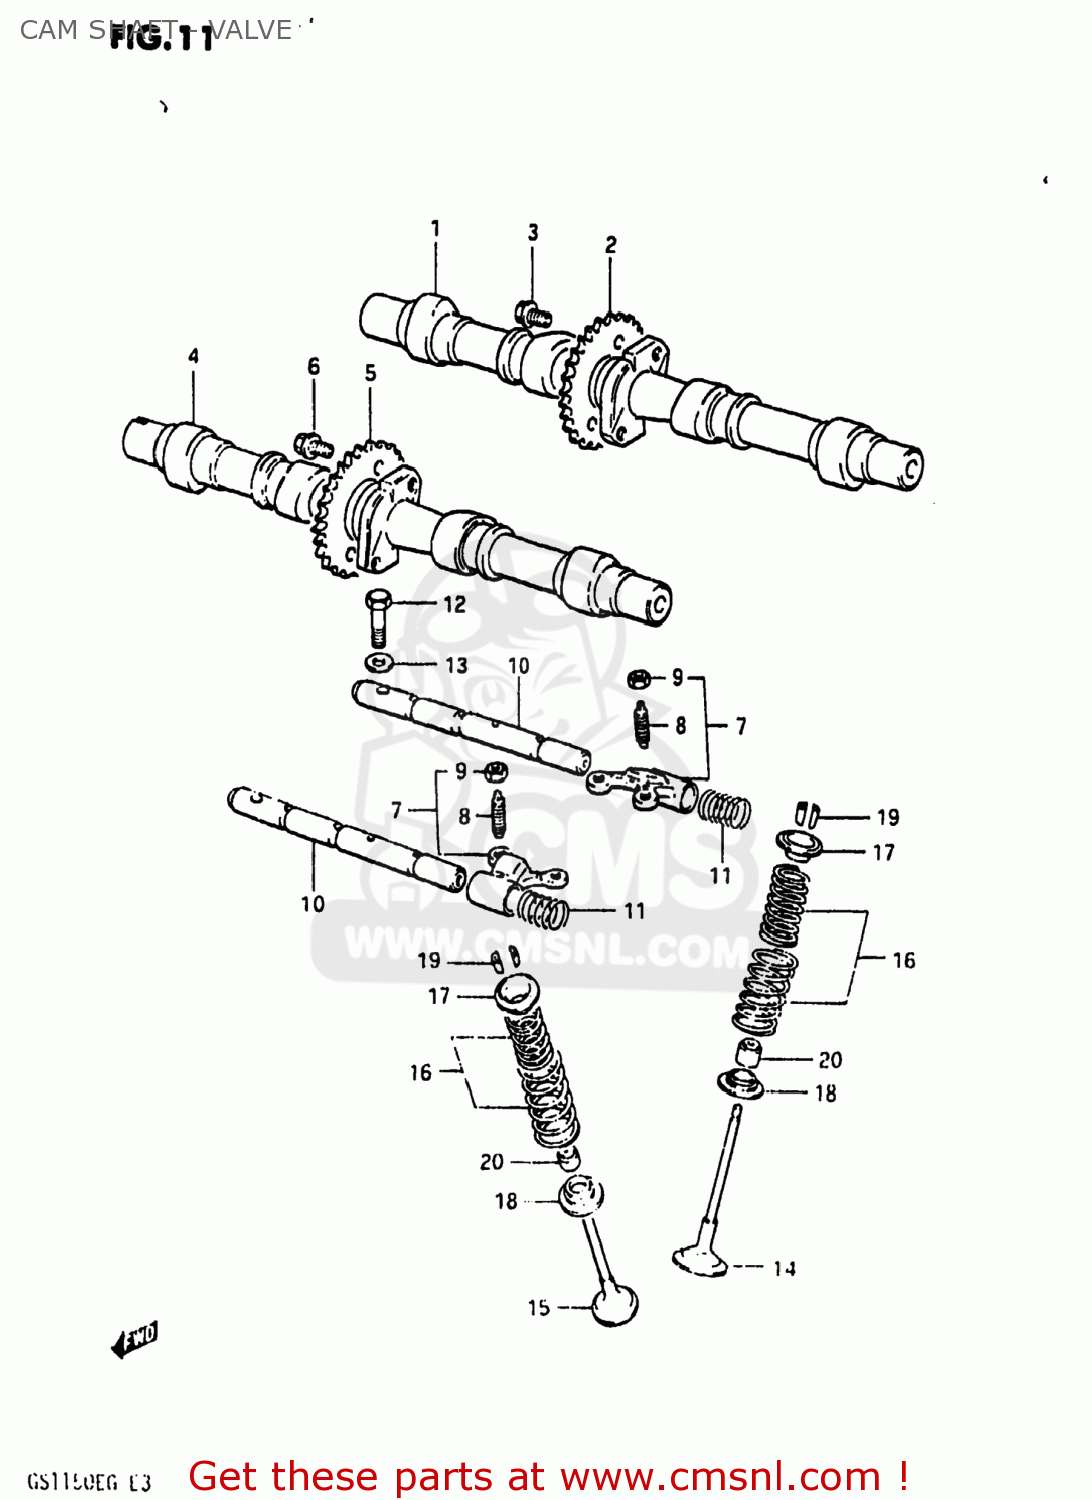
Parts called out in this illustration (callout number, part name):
1	CAMSHAFT,INTAKE
2	SPROCKET,INTAKE CAMSHAFT
3	BOLT(7X11)
4	CAMSHAFT,EXHAUST
5	SPROCKET,INTAKE CAMSHAFT
6	BOLT(7X11)
7	ARM,VALVE ROCKER
8	SCREW,TAPPET ADJUSTING
9	NUT,ADJUSTING
10	SHAFT,VALVE ROCKER
11	SPRING
12	BOLT
13	WASHER, LOWER
14	VALVE,INTAKE
15	VALVE,EXHAUST
16	SPRING SET,VALVE
17	RETAINER,VALVE SPRING
18	SEAT,VALVE SPRING
19	COTTER VALVE
20	OIL SEAL
